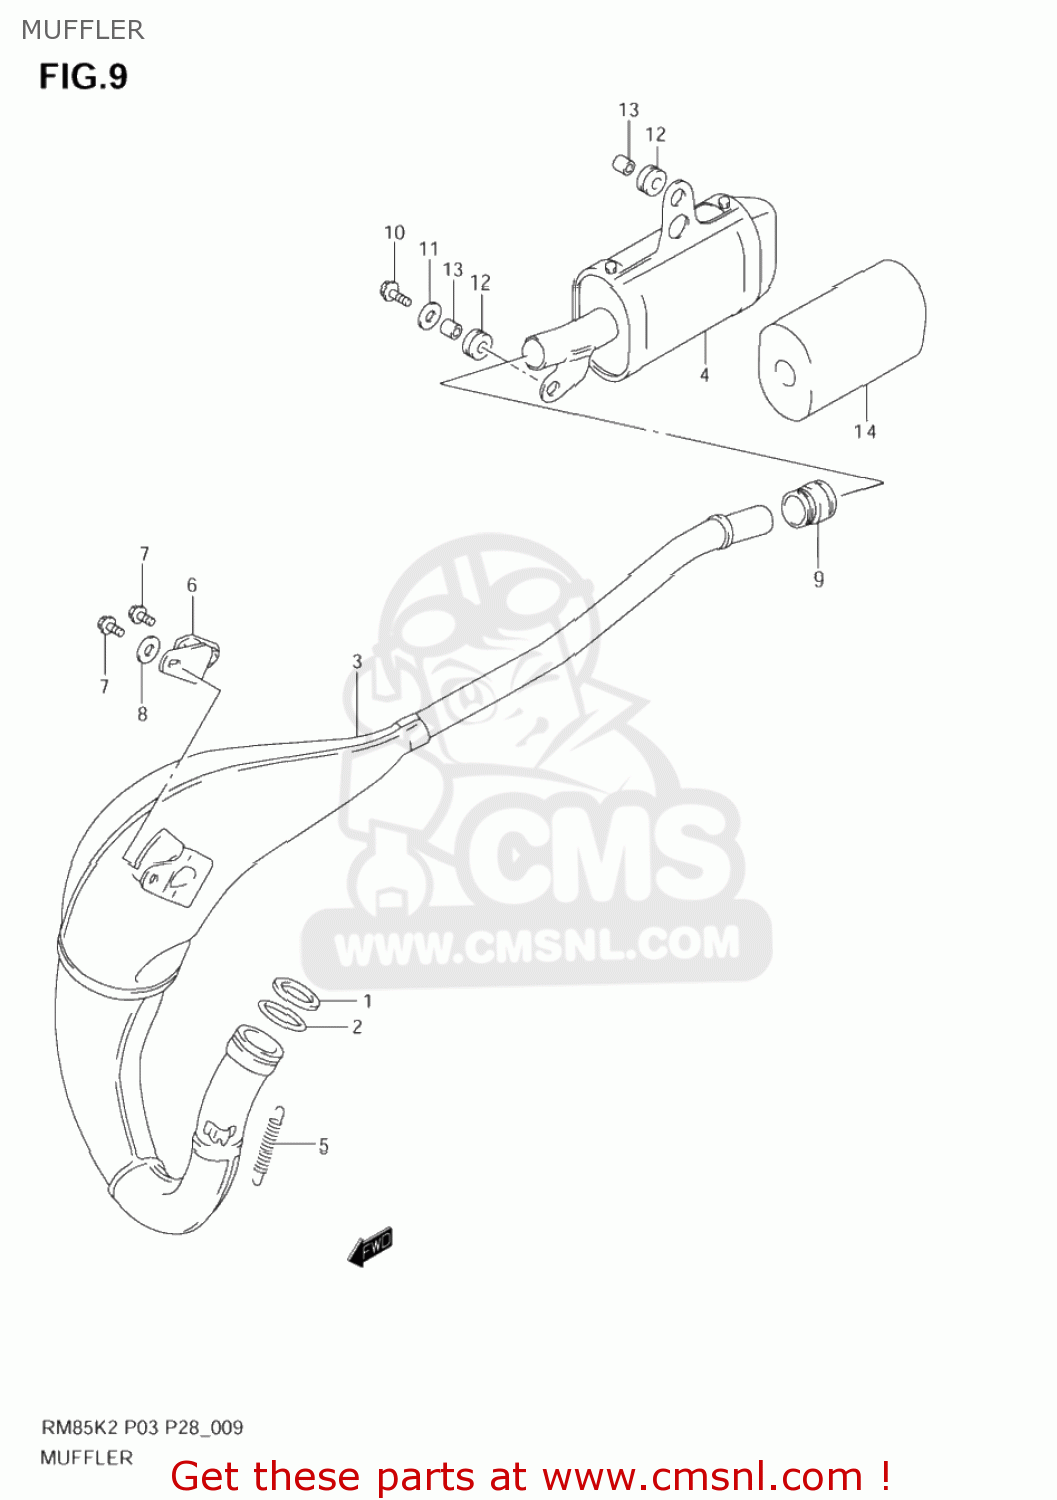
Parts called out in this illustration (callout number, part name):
1	GASKET,EXHAUST PIPE (NAS)
2	O RING,EXHAUST FLANGE
3	BODY,MUFFLER,1
4	BODY,MUFFLER 2ND
5	SPRING
6	DAMPER,MUFFLER
7	BOLT(6X12)
8	WASHER(6.5X16X1.2)
9	CONNECTOR,MUFFLER
10	BOLT,6X20
11	WASHER(6.5X20X1.2)
12	CUSHION
13	SPACER(6.5X9X8)
14	SILENCER,MUFFLER
